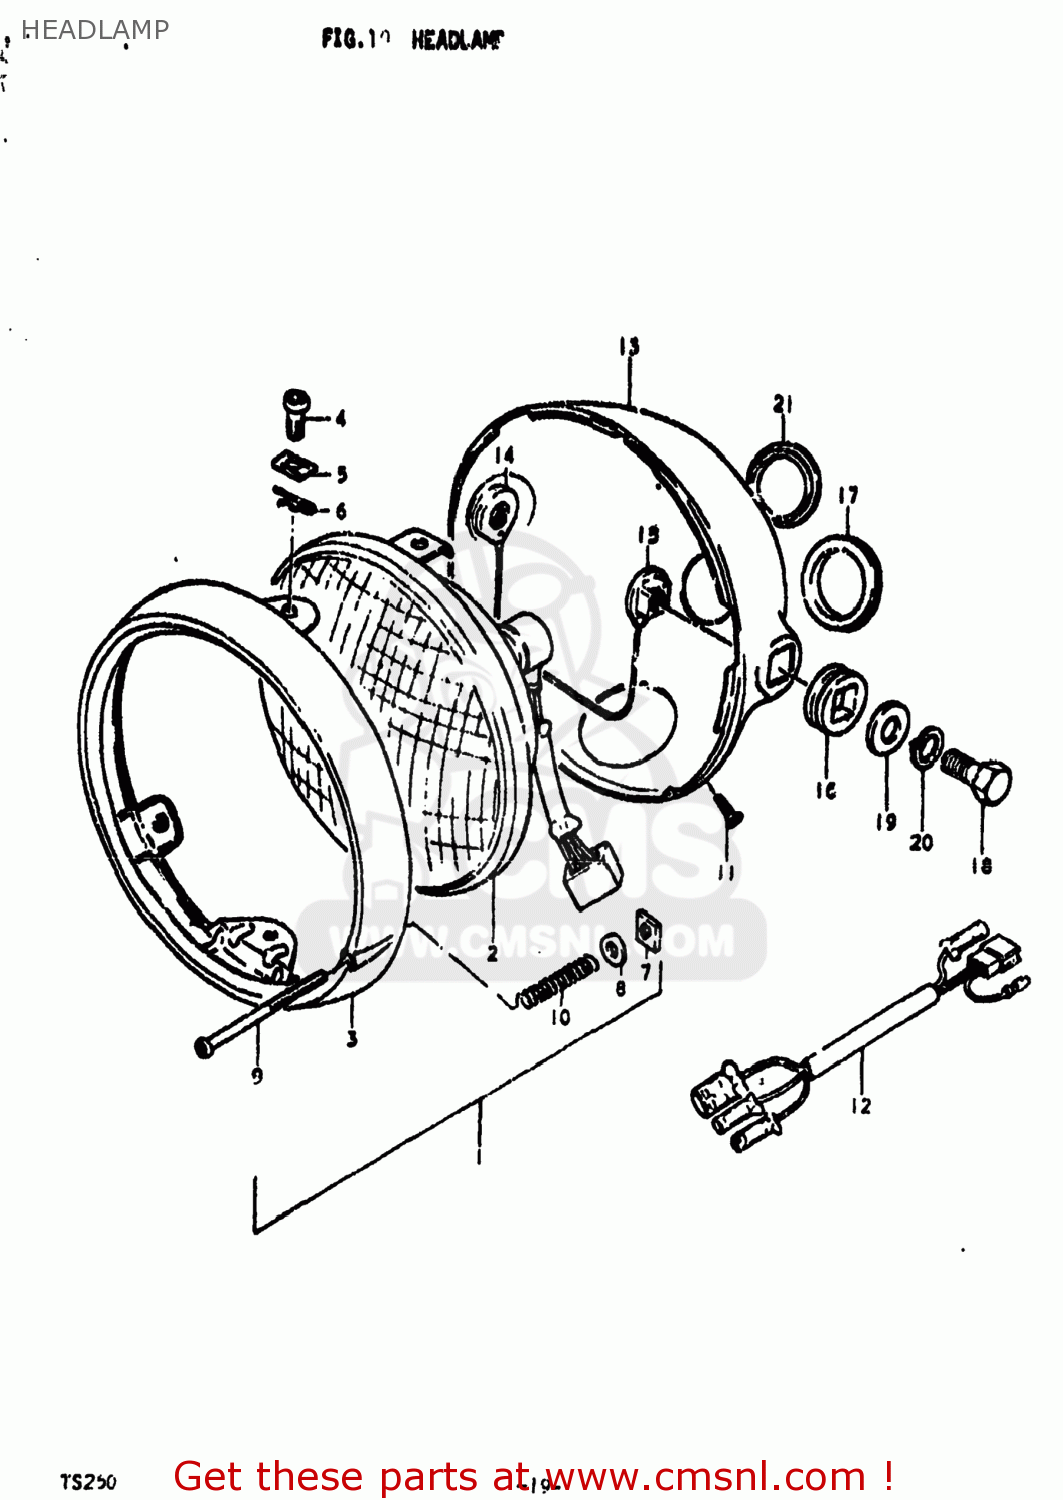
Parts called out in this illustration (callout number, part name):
1	HEADLAMP ASSEMBLY
2	LAMP UNIT
3	RIM,HEADLAMP
4	SCREW
5	NUT,ADJUSTING
6	CUSHION,HEADLAMP
7	NUT,HEADLAMP ADJUSTER
8	WASHER
9	SCREW,HEADLAMP ADJUST
10	SPRING,HEADLAMP ADJUST
11	SCREW(5X12)
12	WIRE
13	HOUSING COMP,HEADLAMP
14	SPACER, HOUSING RH
15	SPACER, HOUSING LH
16	CUSHION,HEADLAMP HOUSING
17	GROMMET,HEADLAMP HOUSING
18	BOLT
19	WASHER
20	LOCK WASHER
21	CAP
